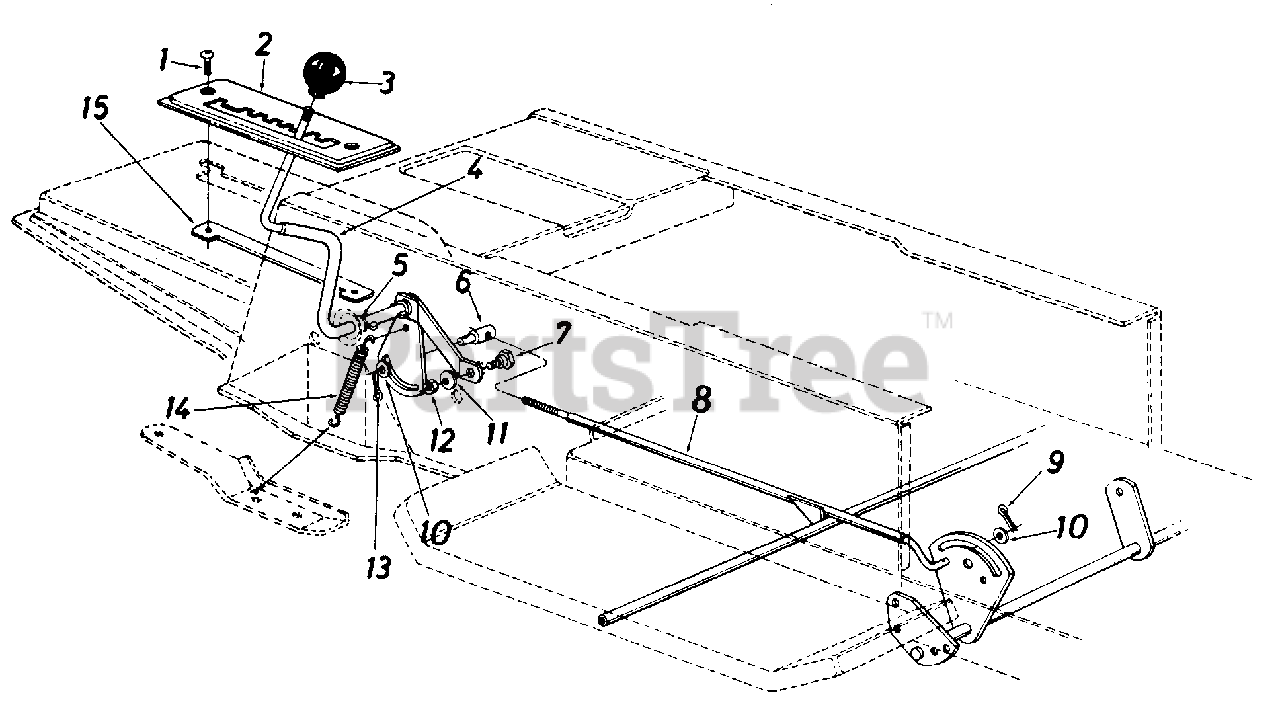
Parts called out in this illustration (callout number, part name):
1	Truss Mach. Scr. 1/4-20 x .75" Lg.
2	Speed Selector Plate 4-Speed
4	Speed Selector Cam Ass'y.
5	Flat Washer .53" I.D. x .93" O.D.
6	Ferrule 3/8-24 x .37" Dia.
7	Shoulder Bolt .435" Dia. x .160
8	Speed Control Rod Ass'y.
9	Cotter Pin 3/32" Dia. x .75" Lg.*
10	Fl-Wash . .469" I . D. x .88" O.D.
11	L-Wash. 5/16" I.D.
12	Hex Nut 5/16-18 Thd.
13	Cotter Pin 3/32" Dia. x .75" Lg.*
14	Spring .38" O.D. x 3.18" Lg.
15	Clamping Plate
